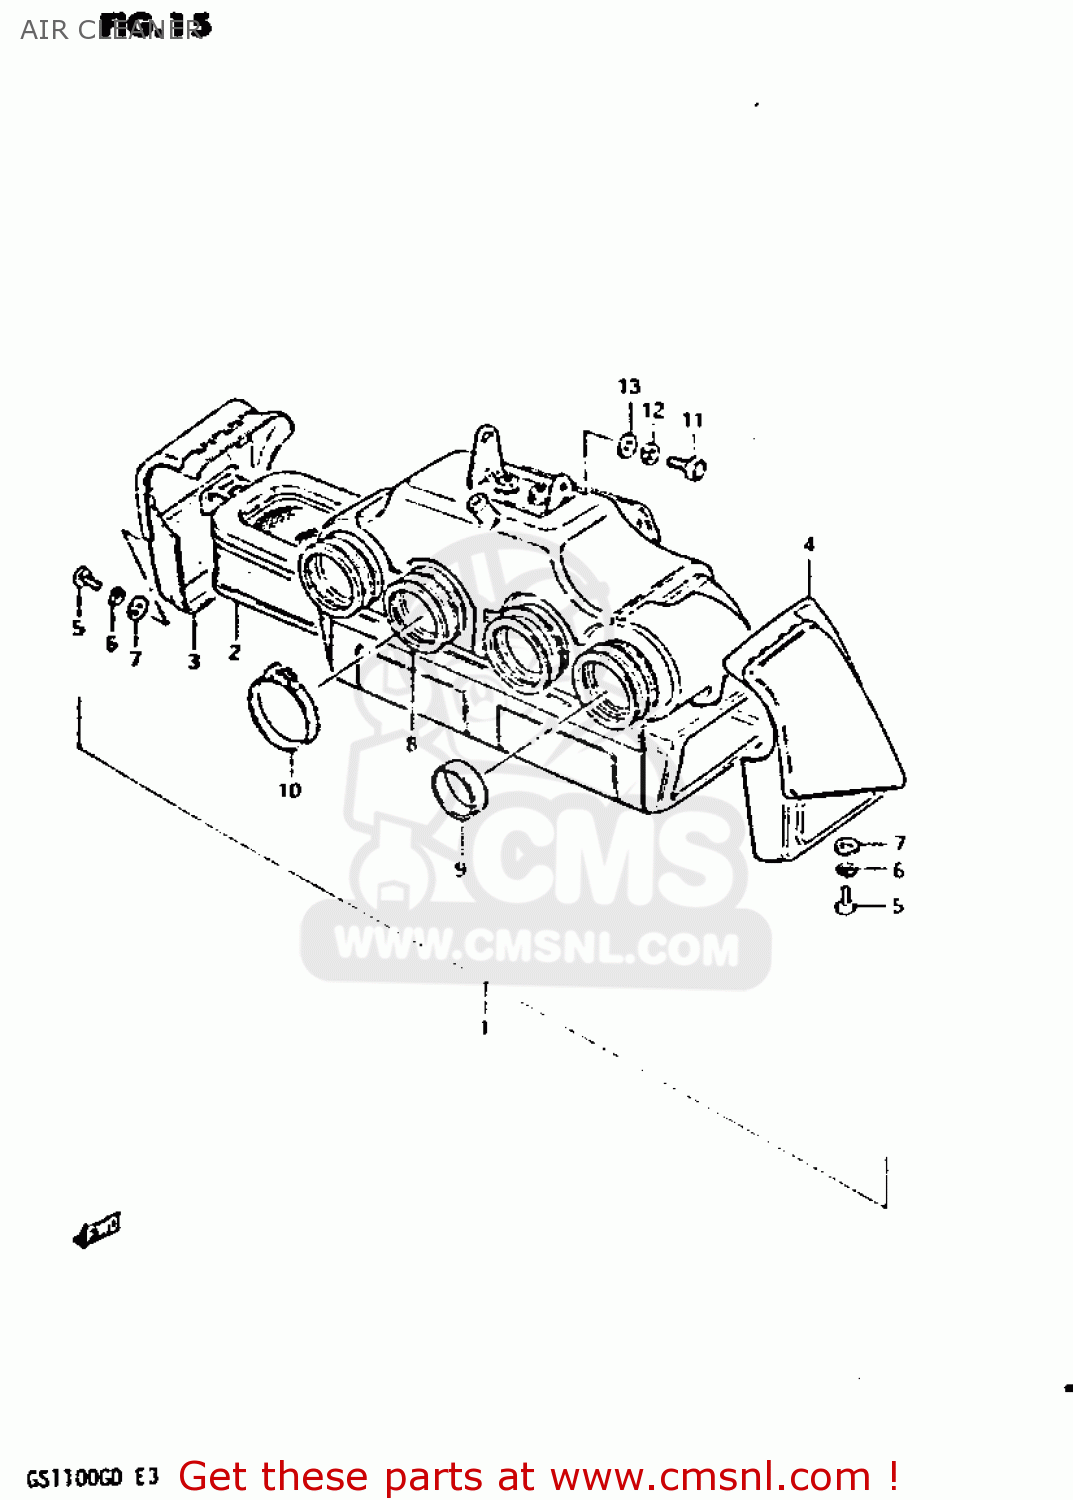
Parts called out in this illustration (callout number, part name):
1	CLEANER ASSEMBLY,AIR
2	FILTER ASSY
3	CAP,AIR CLEANER
4	CAP,AIR CLEANER
5	SCREW
6	LOCK WASHER
7	WASHER
8	TUBE,OUTLET
9	RING,CARBURETOR AIR IN
10	CLAMP
11	BOLT
12	WASHER,LOCK
13	WASHER 6MM
